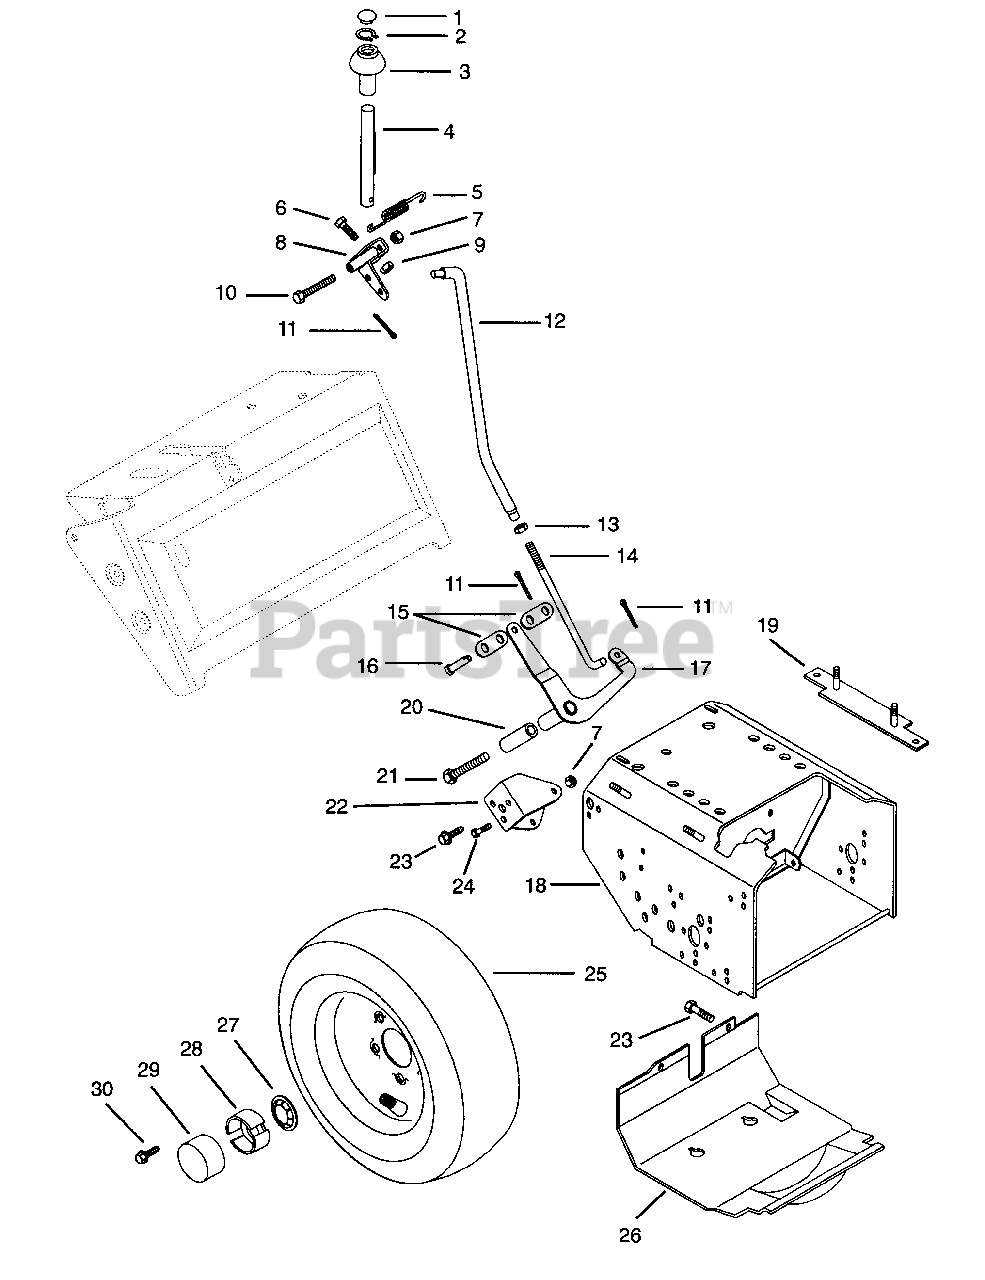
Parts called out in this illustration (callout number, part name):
1	HOLE PLUG
2	RG-RTNG-EXT .500X.015
4	ROD
5	SG-TENS .055X.33X1.31 WLD 7
6	BLT-HEX .25-20X1.0 YWZC
7	@NUT-LK-CTR .31-18 YWZC
9	@NUT-LK-CTR .25-20 YWZC
10	@BLT-HEX .31-18X3.50 GR5 YWZC
11	@PIN-CTR .09X.75 EXTPRSQCT YWZ
12	UPPER SHIFT ROD
13	NUT-HEX .312-24 YWZC
14	LOWER SHIFT ROD
15	SHIFT LINK
16	CLEVIS PIN
17	LEVER - SHIFT ARM
18	FRAME
19	BOLT STRAP
20	SPACER .5 X .33 X 2.4
21	@BLT-HEX .31-18X3.00 GR5 YWZC
22	BRACKET SHIFT LEVER
23	@SCR-TAP .31-18X.50 HWH TR YWZ
24	@BLT-HEX .31-18X.50 GR5 YWZC
25	TUBE
25	WHL
25	TIRE 4.80-8 NHS
25	TIRE 16X6.50-8 SNO-HOG TREAD
25	T/WHL ASSY 4.80-8
25	T/WHL ASSY 16X6.50-8 SNO-HOG
26	BOTTOM COVER
27	PUSHNUT
28	SPINDLE CUP
29	HUB CAP
30	SCR-TAP .500-20X.62 HH YWZC
